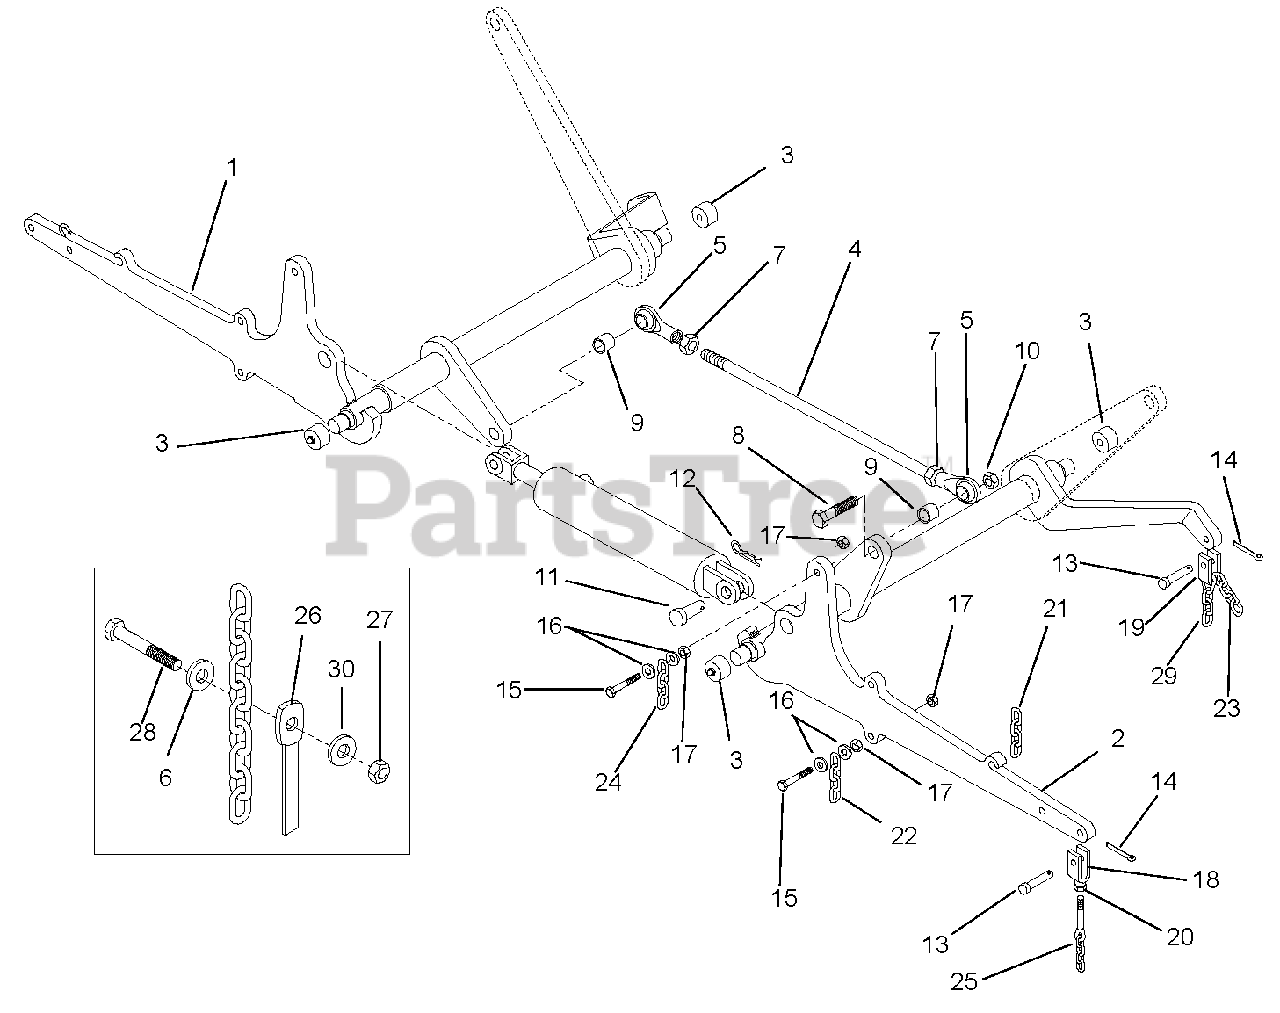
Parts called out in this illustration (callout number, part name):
1	Weldment, Hydraulic Lift Arm Left Hand (895405, 435)
2	Weldment, Hydraulic Lift Arm Right Hand (895405, 435)
3	Assembly, Bearing Cup
4	Rod, Synchronizing
5	Rod End .75
6	Washer, Fender .25
7	Nut, Jam .75
8	Cap Screw .75-10 x 3
9	Spacer, Equalizer Rod
10	Nut, Hex .75-10
11	Pin, Clevis 1 x 2.25
12	Pin, Cotter Hair .125
13	Pin, Clevis .375 x 1
14	Cotter Pin 5/32 x 1
15	Cap Screw, Hex Head .375-16 x 1.75
16	Washer, Flat .375
17	Nut, Jam .375-16
18	Clevis Yoke, Modified
19	Clevis Yoke
20	Nut, Hex .375-16
21	Chain, Transport
22	Lift Chain, #1
23	Lift Chain, #2 and #3 Outer
24	Lift Chain, #4 and #5 Inner
25	Lift Chain Weldment, #4 and #5 Outer
26	Strap, Tarp 8.25" No Hook
27	Nut, Hex .25-20 Nylock
28	Hex Head Cap Screw .25-20 x 1-1/2
29	Lift Chain, #2 and #3 Inner
30	Washer, Flat .25
